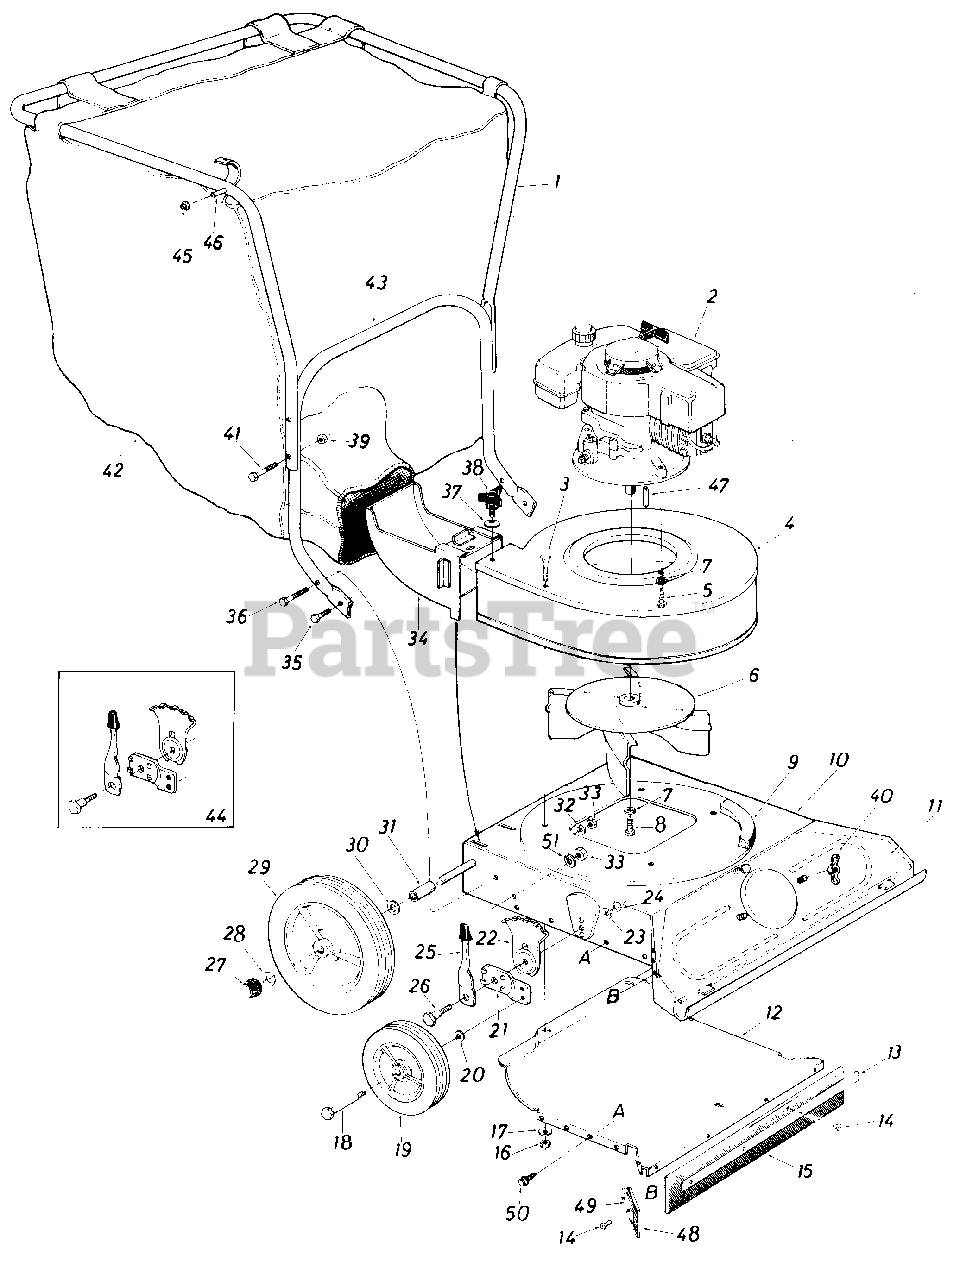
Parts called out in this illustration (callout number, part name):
1	Upper Handle (Painted)
2	Engine
3	Carriage Bolt 5/16-18 x .62" Lg.*
4	Blower Housing Ass'y.
5	Hex Tap Scr. 3/8-16 x 1.00" Lg.
6	Impeller Ass'y.
7	L.-Wash. 3/8" I.D.*
8	Hex Bolt 3/8-24 x 1.0" Lg. w/Patch
9	P.V.C. Foam Strip (4-Pcs. 12" Lg.)
10	Vacuum Deck Ass'y.
11	Front Baffle Ass'y.
12	Lower Baffle Ass'y.
13	Wiper Retaining Strip
14	Pop Rivet .188" Dia.
15	Nozzle Wiper Rear
16	Hex Nut 5/16-18 Thd.*
17	Bell.-Wash. .34" I.D. x .87" O.D.
18	Shld. Bolt 1/2" Dia. x 1.45" Lg. (3/8-16)
19	Wheel Ass'y. Comp. 8 x 1.75"-Front
20	Bell.-Wash. .39" I.D. x 1.12" O.D.
21	Wheel Pivot Bar
22	Index Plate
23	Bell.-Wash. .39" I.D. x 1.12" O.D.
24	Hex Nut 3/8-16 Thd.*
25	Spring Lever Ass'y. w/Knob
26	Shoulder Bolt .500" x 7/16" Lg. (3/8-16)
27	Push Cap .50" Rod (Black)
28	Fl.-Wash. 1/2" I.D. x 1.0" O.D. x .06
29	Wheel Ass'y. Comp. 10 x 1.75"-Rear
30	Fl.-Wash. 1/2" I.D. x 1.0" O.D. x .06
31	Wheel Spacer 1/2" I.D. x 15/16" Lg.
32	Bell.-Wash. .39" I.D. x 1.12" O . D.
33	Hex Nut 3/8-16 Thd.*
34	Air Duct Ass'y.
35	Hex Bolt 3/8-16 x .75" Lg.*
36	Hex Bolt 3/8-16 x 1.50" Lg.*
37	Bell.-Wash. .34" I.D. x .87" O.D.
38	Thumb Scr. 5/16-18 x .75" Lg.
39	Hex Cent. L.-Nut 1/4-20 Thd.
40	Wing Nut 1/4-20 (Plastic)
41	Hex Bolt 1/4-20 x 1.75" Lg.*
42	Vacuum Bag (6.6 Bushel)
43	Lower Handle (Painted)
44	Height Adjuster Ass'y. Comp.-R.H.
45	Push Speed Nut .25" Dia.
46	Stud Pin .250" Dia. x 1.75" Lg.
47	Sq. Key 3/16 x 3/16 x 1.00" Lg.
48	Nozzle Wiper Side
49	Wiper Retaining Strip
50	Hex Wash. Hd. "F" Tap Scr. #1 0
51	L-Wash. 3/8" I.D.*
